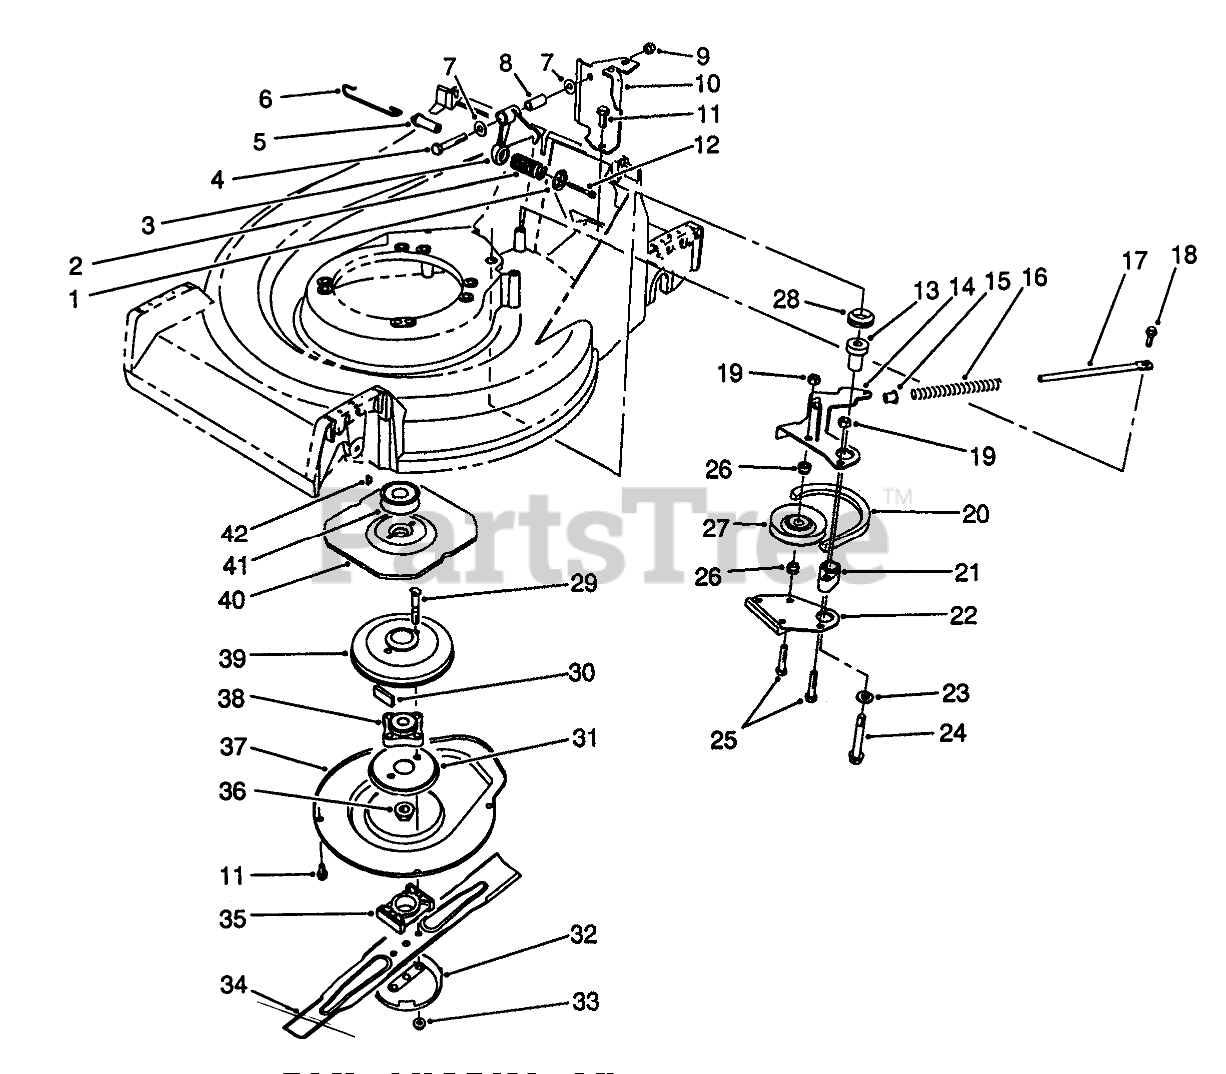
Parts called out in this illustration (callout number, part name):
1	RETAINER-SPRING
2	COMPRESSION SPRING
3	CRANK
4	SCREW-HH
5	SPRING PIN
6	CONTROL LINK
7	WASHER-PLAIN
8	STRAIGHT BUSHING
10	Bracket-Cable Support
11	SCREW-HWHTF
12	SCREW-HWHTF
13	BBC PM BUSHING
14	Lever
15	SPACER
16	COMPRESSION SPRING
17	SPRING ROD
18	SCREW-SHOULDER
19	NUT-LOCK, NI
20	V-BELT
21	BRAKE PLATE HUB
22	BRAKE SHOE
23	WASHER-PLAIN
24	3/8-16 X 2-3/4 CAPSCR
25	SCREW-HH
26	IDLER PULLEY HUB
27	PULLEY-IDLER
28	V-RING SEAL
29	BOLT-BLADE
30	DAMPENER-VIBRATION
31	Screen-BBC
32	Anti Scalp Cup
33	NUT-LOCK
34	Key
35	SPACER-BLADE
36	NUT-LOCK, NI
37	Cover
38	HUB ASM
39	BRAKE DRUM
40	FLYWHEEL - BBC
41	PULLEY
42	KEY-WOODRUFF
